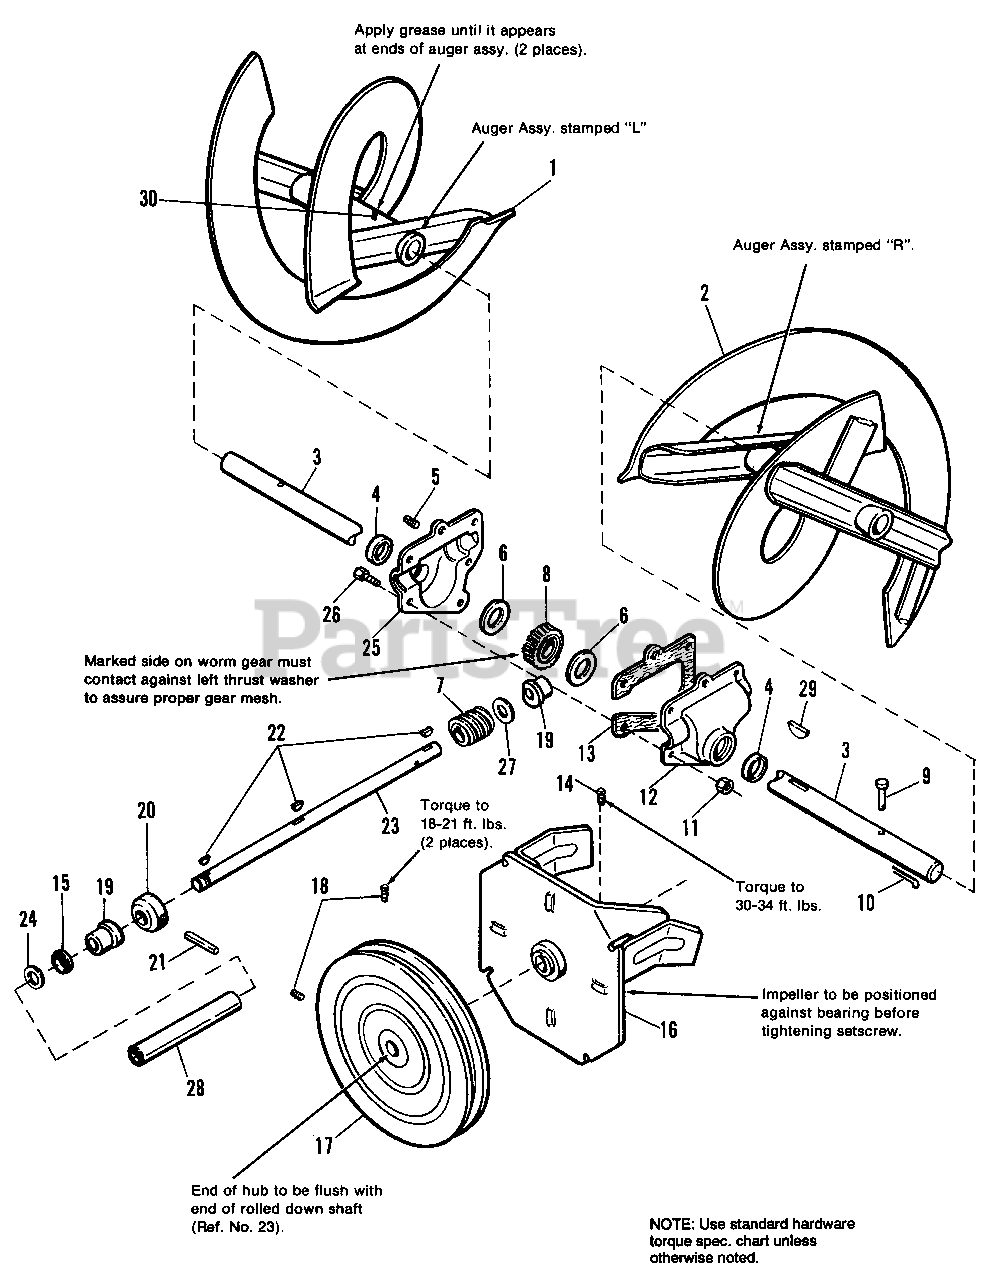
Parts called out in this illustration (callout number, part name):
1	AUGER ASSY., L.H., 24"
1	AUGER ASSY., L.H., 28"
1	AUGER ASSY., L.H., 32"
2	AUGER ASSY., R.H., 24"
2	AUGER ASSY., R.H., 28"
2	AUGER ASSY., R.H., 32"
3	SHAFT, Auger
5	PLUG, Pipe, Tapered, 1/8
6	WASHER, Thrust
7	GEAR, Rolled Worm
8	GEAR, Worm
9	PIN, Shear
10	PIN, Cotter, 3/32 x 3/4
11	LOCKNUT, Hex, 1/4-20
12	CASE, Gear, R.H.
14	SETSCREW, Sq. Hd., 3/8-16 x 1/2
16	IMPELLER ASSY.
17	PULLEY, Auger Input
18	SETSCREW (Sq. Hd., 5/16-18 x 1/2
19	BUSHING, Flange
20	COLLAR, Thrust
21	PIN, Drivelok, 3/16 x 1-1/2
22	KEY, Woodruff, 3/16 x 5/8
23	SHAFT, Worm
24	WASHER
25	CASE, Gear (L.H.)
26	CAPSCREW, Hex Hd.,1/4-20 x 7/8
27	WASHER, Thrust
29	KEY, Woodruff, 1/4 x 3/4
30	GREASE FITTING
